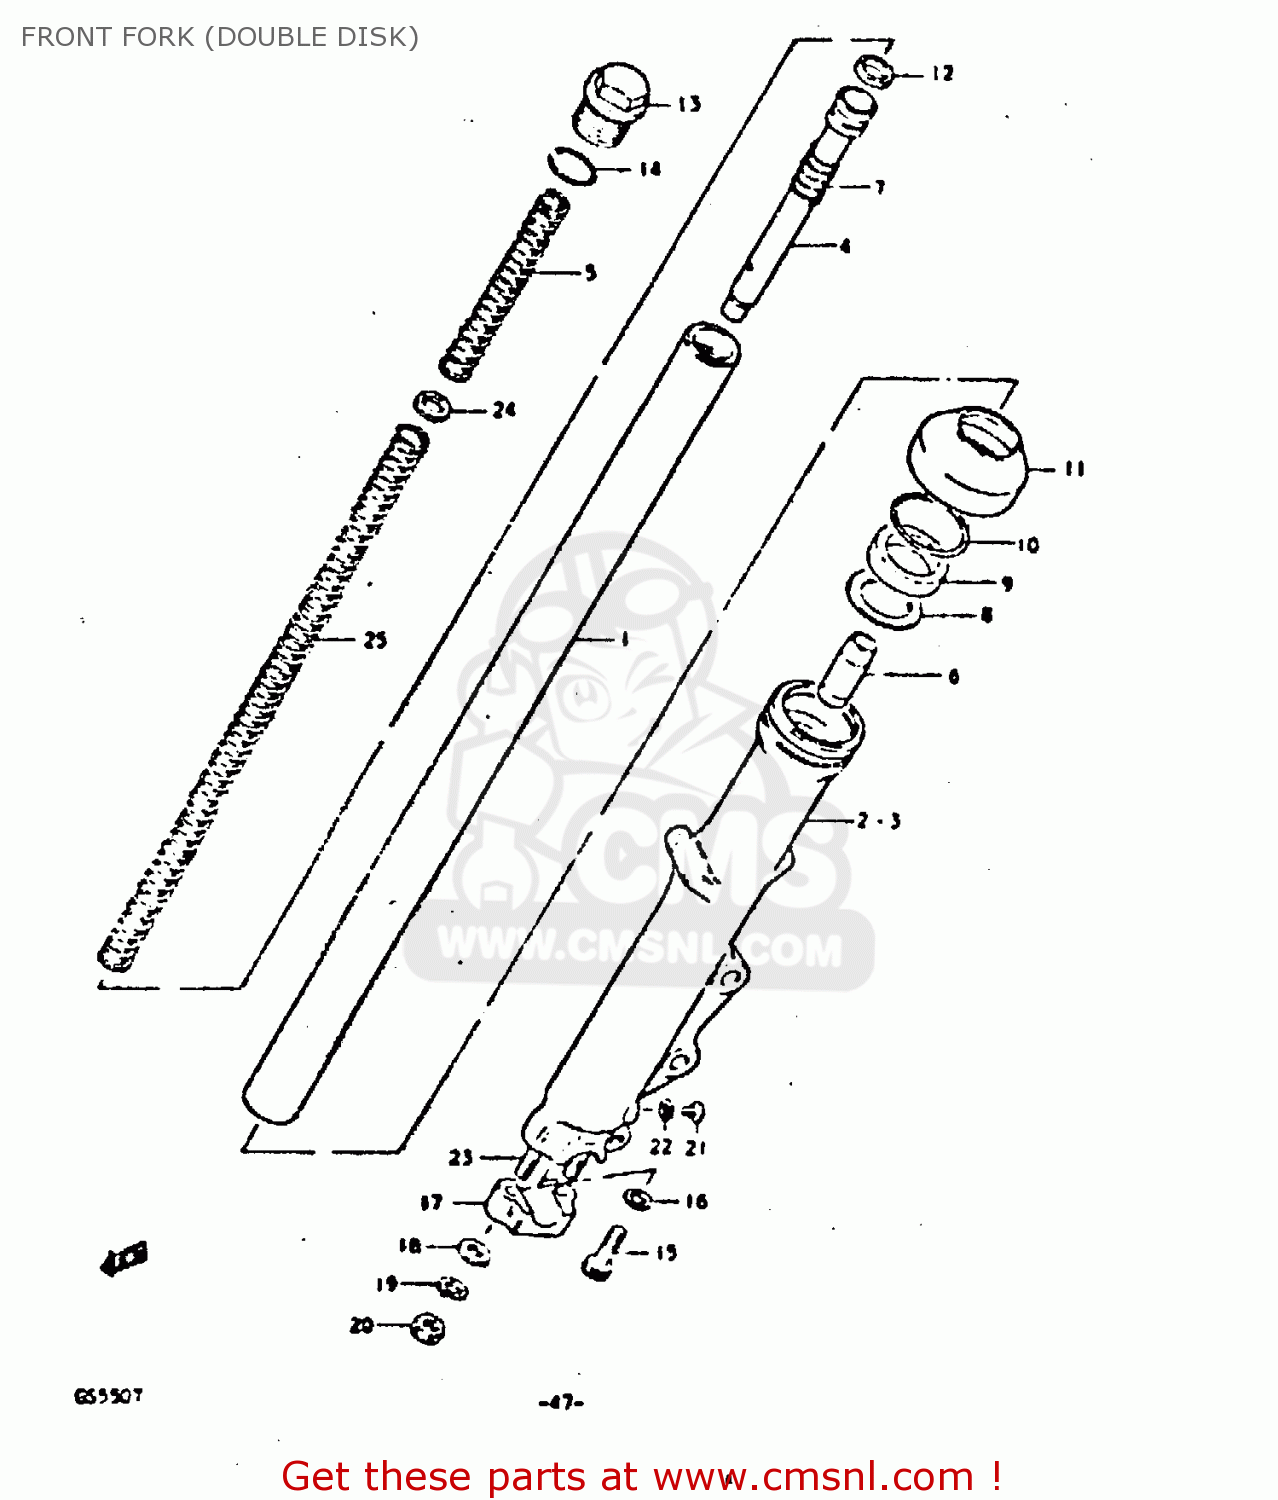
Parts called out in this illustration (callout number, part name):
1	TUBE,FORK,INNER
2	TUBE,FORK,OUTER,RIGHT
3	TUBE,FORK,LEFT,OUTER
4	SEAT,FRONT FORK,UNDER
5	SPRING,FRONT FORK,UPPER
6	PIECE,OIL LOCK
7	SPRING,FORK REBOUND
8	SPACER,SEAL
9	OIL SEAL,FRONT FORK
10	CIRCLIP,FORK OIL SEAL
11	BOOT
12	RING
13	CAP,INNER TUBE
14	O RING
15	BOLT(8X27)
16	GASKET (NAS)
17	HOLDER,AXLE
18	WASHER
19	LOCK WASHER
20	NUT
21	SCREW 4X6
22	GASKET (NAS)
23	STUD 8X25
24	WASHER
25	SPRING,FRONT FORK MAIN,LOWER
